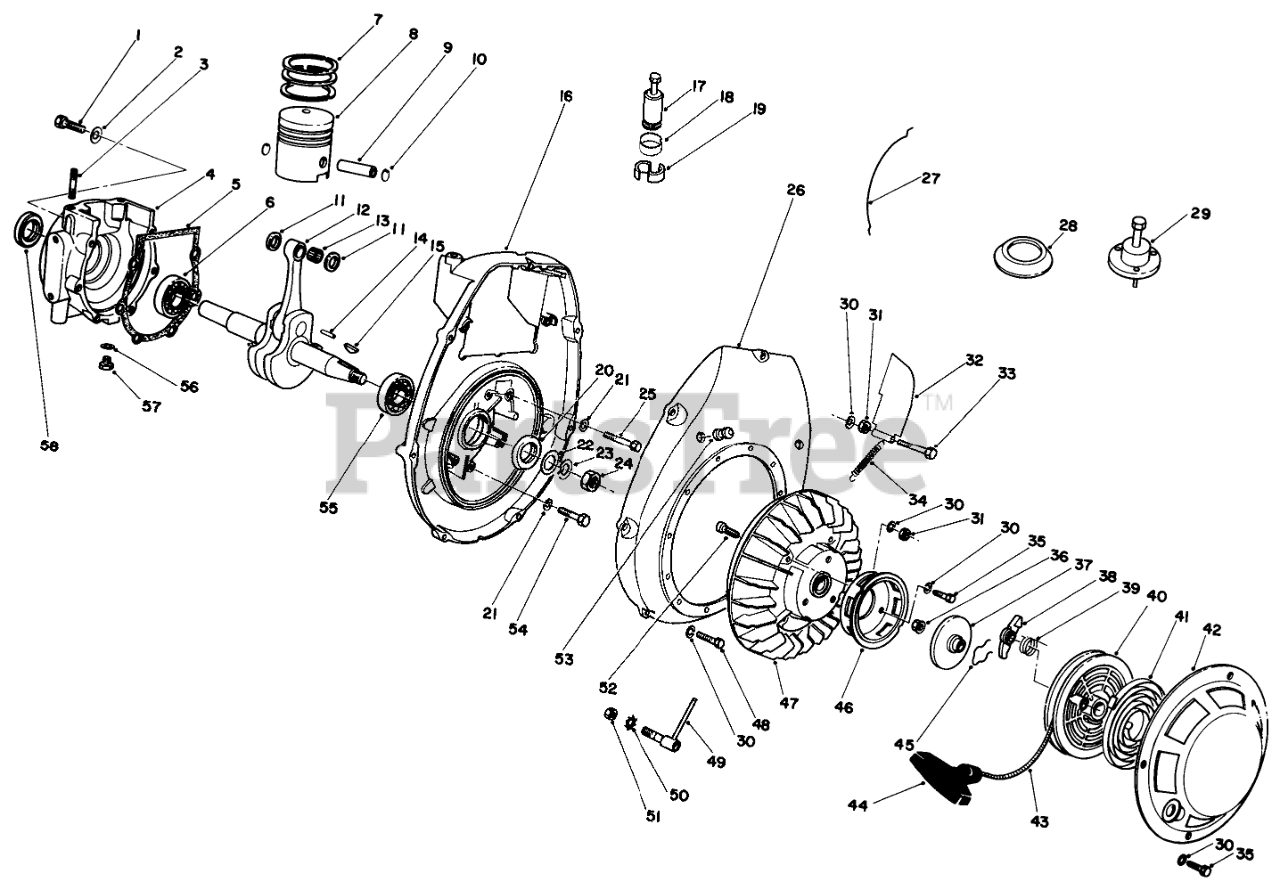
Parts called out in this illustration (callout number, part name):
1	Screw-Hex Head
2	Washer
4	Crankcase-PTO Side
5	CRANKCASE GASKET
6	Ball Bearing
7	Piston Rings
8	Pistons
9	Wrist Pin
10	Locking Ring
11	Washer
12	Crankshaft Assembly
13	Bearing-Needle
14	Needle
15	Key-Woodruff
16	Crankcase Starter Side
17	Extractor
18	Retaining Ring
19	Half Bushes (Pair)
20	Oil Seal
21	Lockwasher
22	Washer
23	Washer
25	Screw-Hex Head
26	Cover-Fan
27	Control Cable
28	Meter-Revolution Frequency
29	Puller
30	Lockwasher
32	Air Vane
33	Screw-Hex Head
34	Spring
35	Screw-Hex Head
37	Brake-Disc
39	Spring
40	Pulley-Rope
41	Recoil Spring
42	Housing-Starter
43	Rope (Incl. Ref. #44)
44	Handle
45	SPRING
46	Carrier
47	Fan Wheel
48	HEX HEAD SCREW
49	LEVER
50	Star Washer
52	Screw
54	Screw-Hex Head
55	Ball Bearing
56	Gasket Ring
57	Screw-Hex Head
58	Oil Seal
